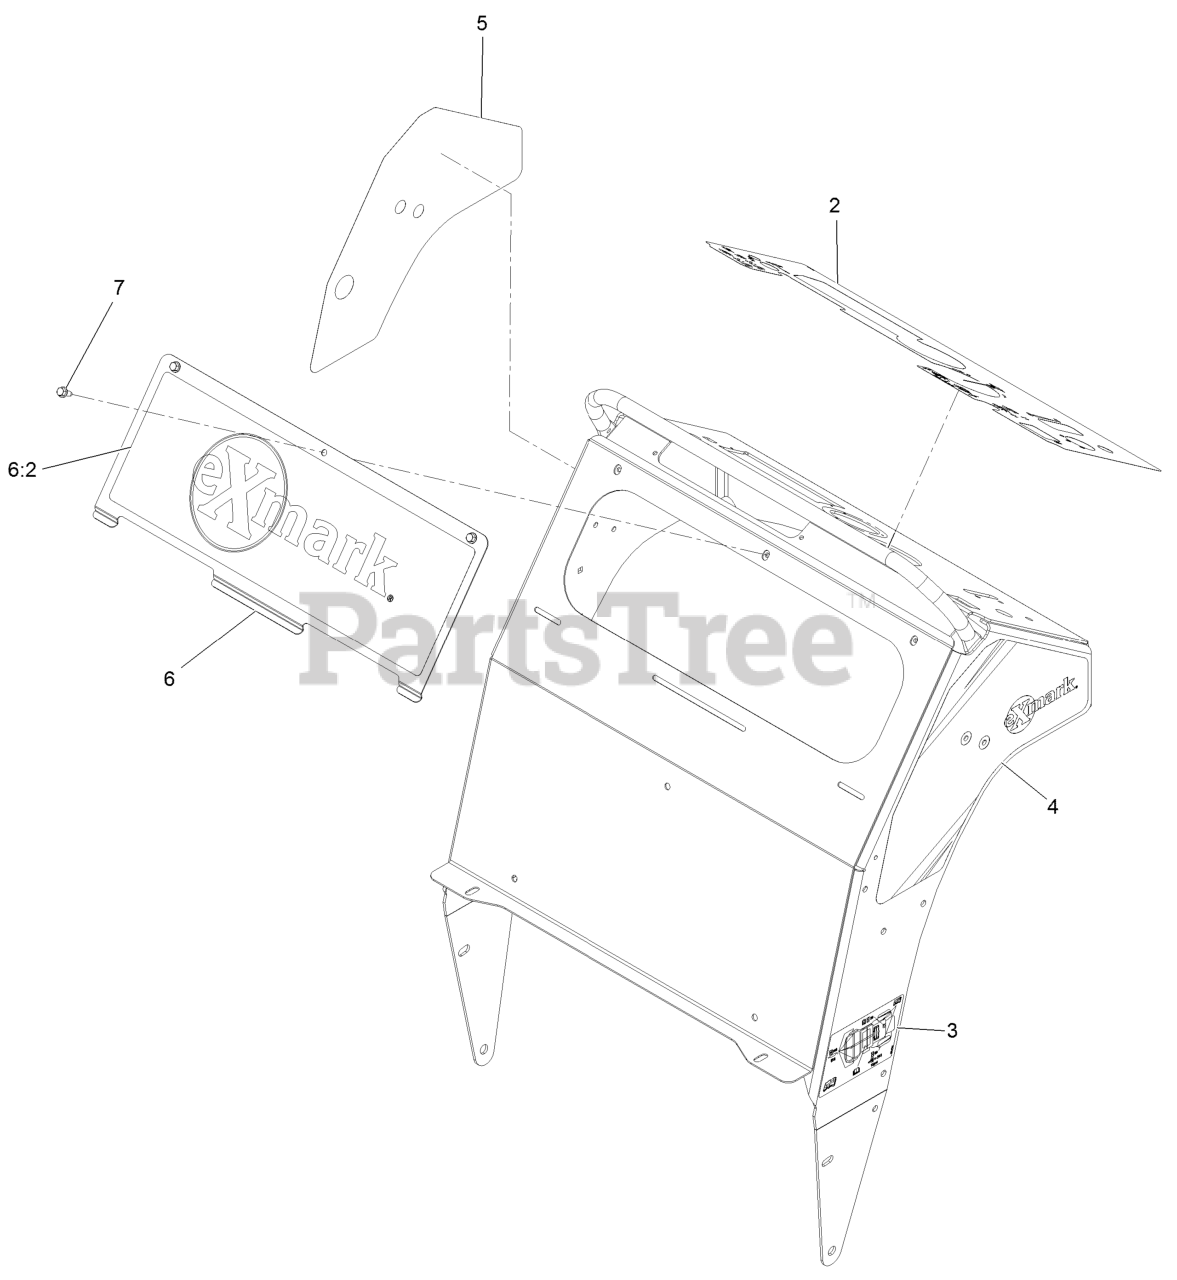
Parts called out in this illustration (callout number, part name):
2	DECAL-CONTROL
3	DECAL-SERVICE AID
4	DECAL-LH SIDE PANEL
5	DECAL-RH SIDE PANEL
6	ACCESS PANEL W/ DECAL
6:2	Decal-Exmark Front Panel
7	SCREW-HWH
